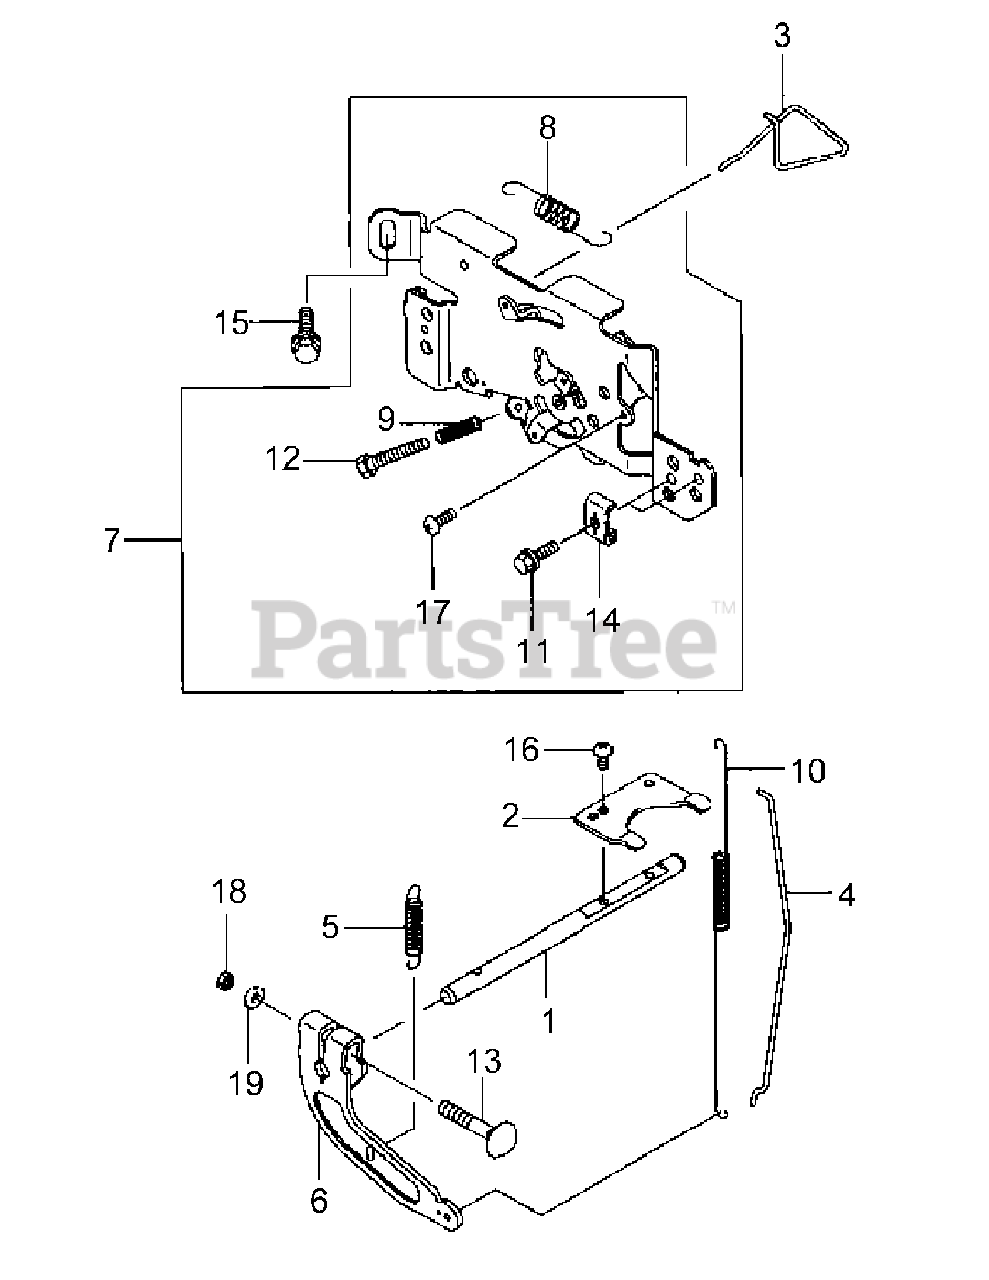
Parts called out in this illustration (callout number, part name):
1	SHAFT
3	CHOKE LINK
4	LINK
5	GOVERNOR SPRING
7	CONTROL PANEL
8	SPRING
13	BOLT, 6x35
15	FLANGED BOLT
19	PLAIN WASHER
